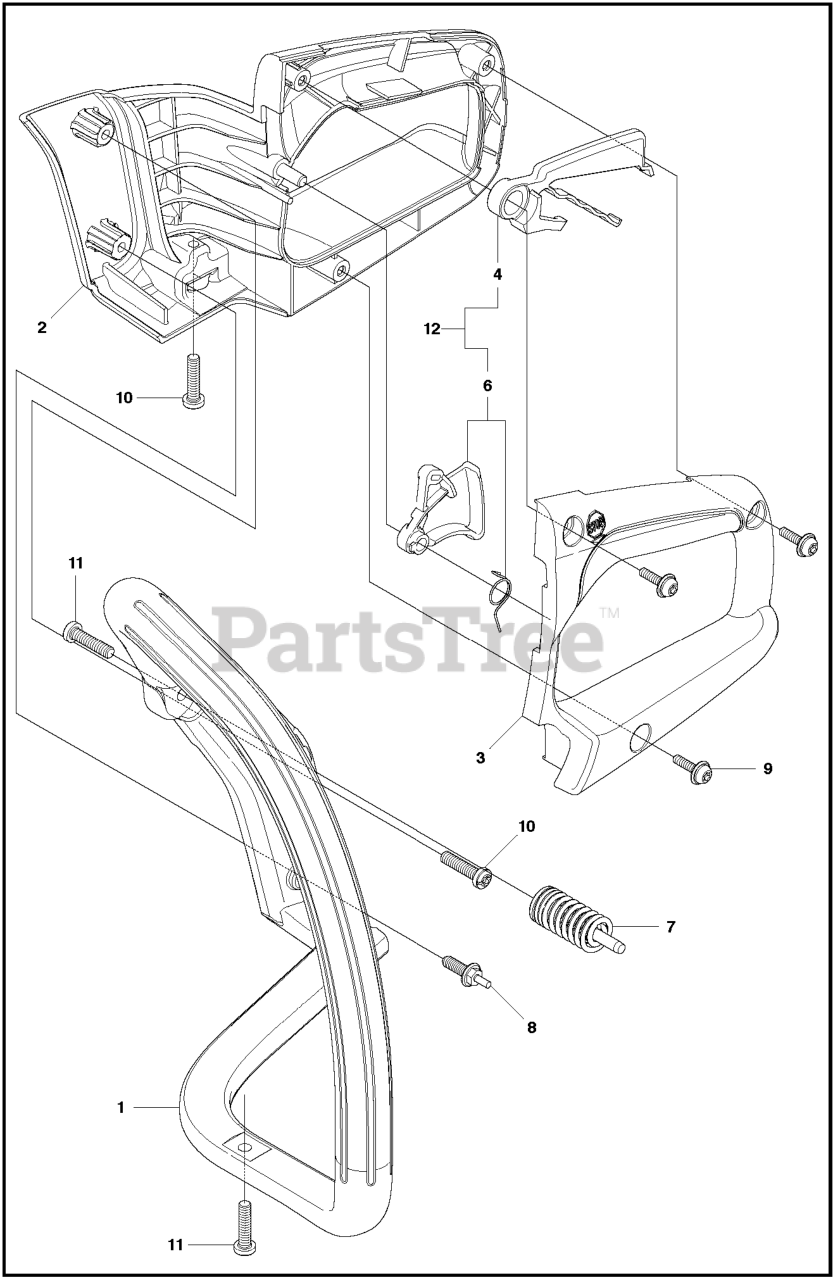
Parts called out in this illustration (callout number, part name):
1	FRONT HANDLE
2	REAR HANDLE
3	COVER REAR HANDLE
4	LOCKOUT - THROTTLE
6	ASSY TRIGGER GRAY
7	SPRING CYLINDER ASSY
10	SCREW FILTER PLATE
11	SCREW M5.38-14X22.225MM
12	TRIGGER & LOCKOUT KIT
